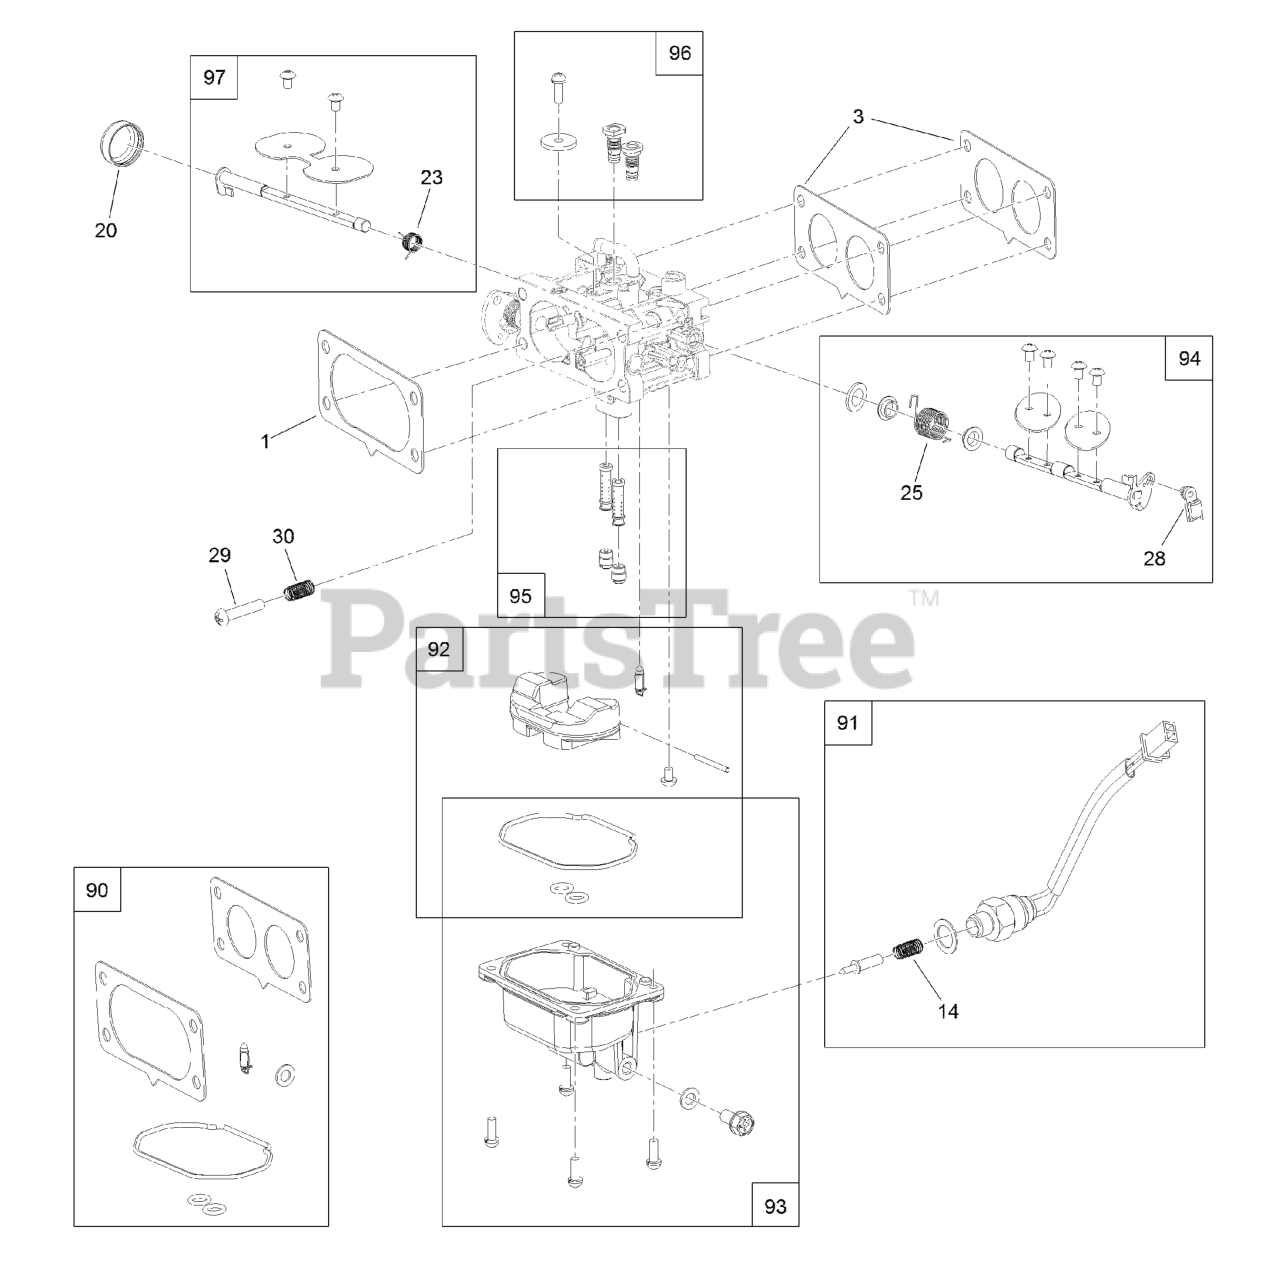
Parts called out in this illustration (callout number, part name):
1	GASKET-CARBURETOR
3	GASKET-CARBURETOR
20	COVER-SHAFT, CHOKE
28	CLAMP-LOCK
29	SCREW-PPH
90	CARBURETOR REPAIR KIT
91	SOLENOID KIT
92	FLOAT KIT
93	BOWL KIT
94	THROTTLE SHAFT KIT
95	NOZZLE AND JET KIT
96	IDLE JET KIT
97	CHOKE SHAFT KIT
